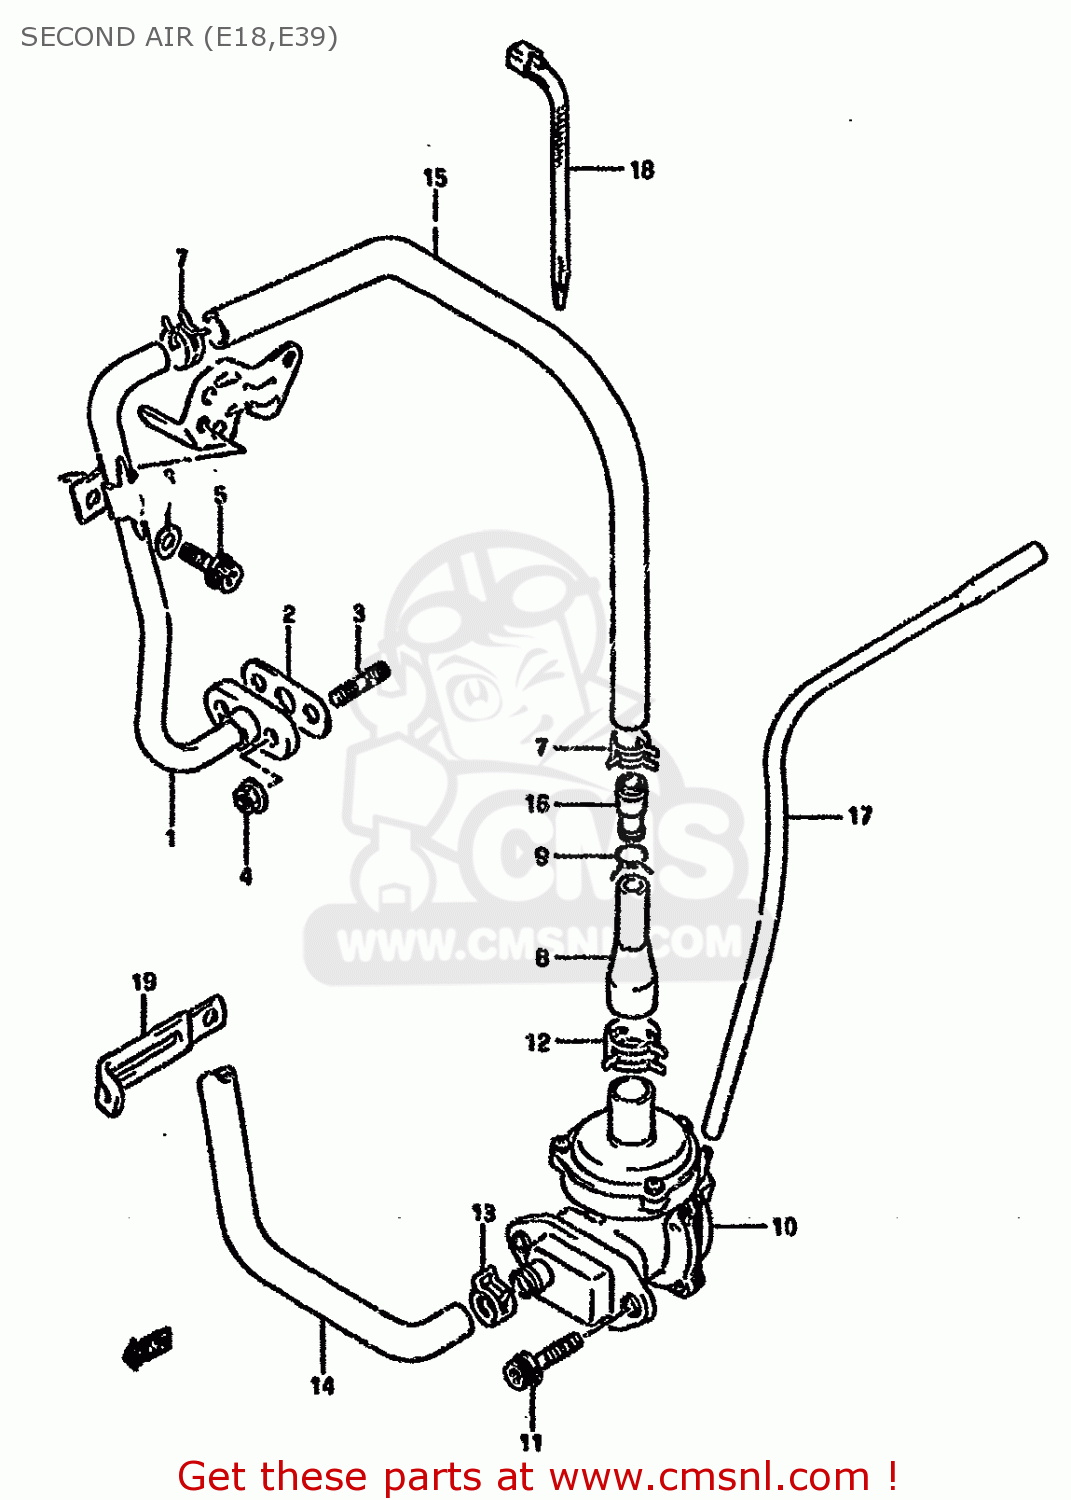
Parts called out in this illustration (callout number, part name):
1	PIPE,2ND AIR
2	GASKET,SECOND AIR PIPE (N (NAS)
3	STUD 6X16
4	NUT
5	BOLT
6	WASHER
7	CLIP
8	HOSE, 2ND AIR
9	CLIP
10	VALVE ASSY, 2ND AIR REED
11	BOLT
12	CLIP
13	CLIP
14	HOSE, 2ND AIR NO.4
15	HOSE,2ND AIR NO.2
16	UNION, 2ND AIR HOSE
17	HOSE(4X7X600)
18	CLAMP
19	CLAMP(L:65)
